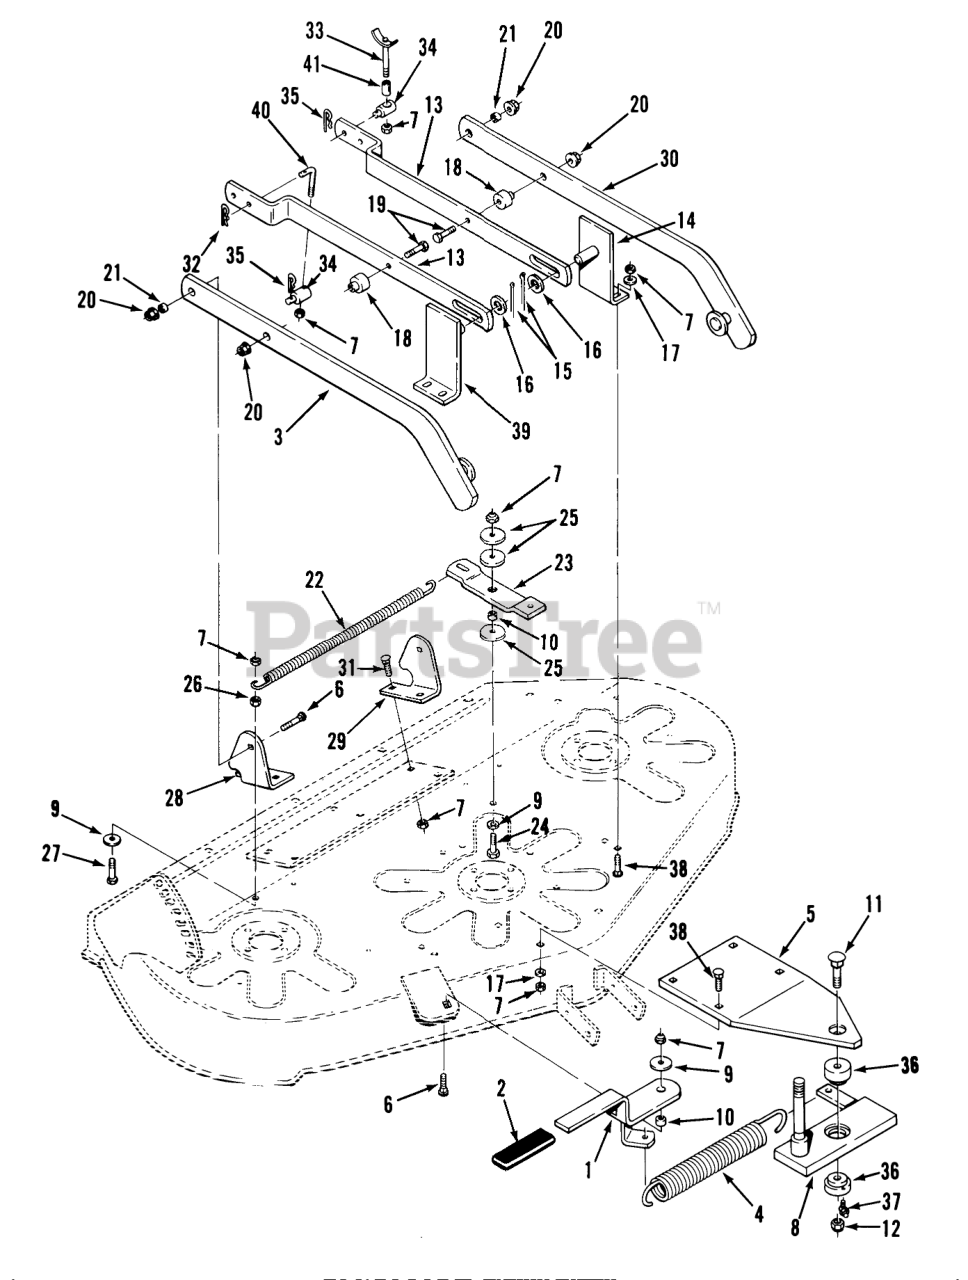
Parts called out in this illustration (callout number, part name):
1	Lever
3	Draft Bar RH
4	Spring
5	Plate
6	Bolt
7	NUT
8	Countershaft
9	WASHER
10	SPACER
11	Bolt
12	Nut
13	Bar-Leveler
14	Bracket
15	PIN-4
16	WASHER
17	Washer
18	SPACER
19	Bolt
20	LOCKNUT-FLANGE
21	SPACER
22	SPRING - EXTENSION
23	Arm-Idler
24	BOLT
25	Washer
26	Nut
27	Bolt
28	Bracket RH
29	Bracket LH
30	Draft Bar LH
31	Carriage Bolt
32	Cotter Pin
33	WLDMT-HANGER ROD
34	Trunion
35	Hairpin
36	BUSHING
37	Fitting-Grease
38	Bolt
39	Bracket RH
40	ROD-LIFT
41	SPACER .375 ID X 1.6
